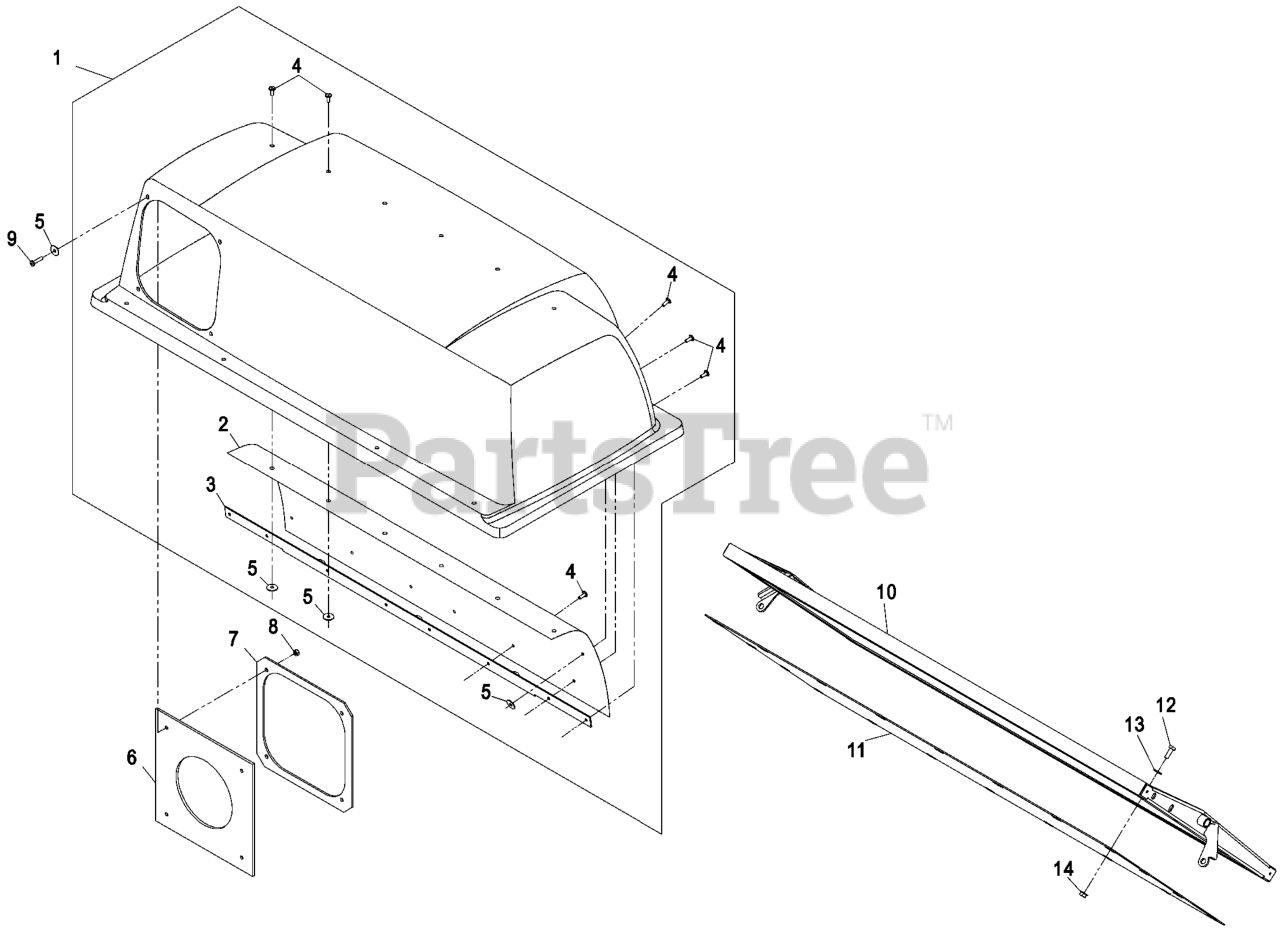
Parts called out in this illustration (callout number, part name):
1	ASM, HOOD
2	SCREEN-BAGGER
3	SUPPORT-SCREEN
4	RIVET-BLIND
5	WASHER-FLAT
6	SEAL-CHUTE
7	CLAMP-SEAL
8	NUT-LOCK, NI
9	SCREW-PPH
10	DOOR-FRAME
11	SCREEN-DOOR
12	SCREW-HH
13	WASHER-FLAT
